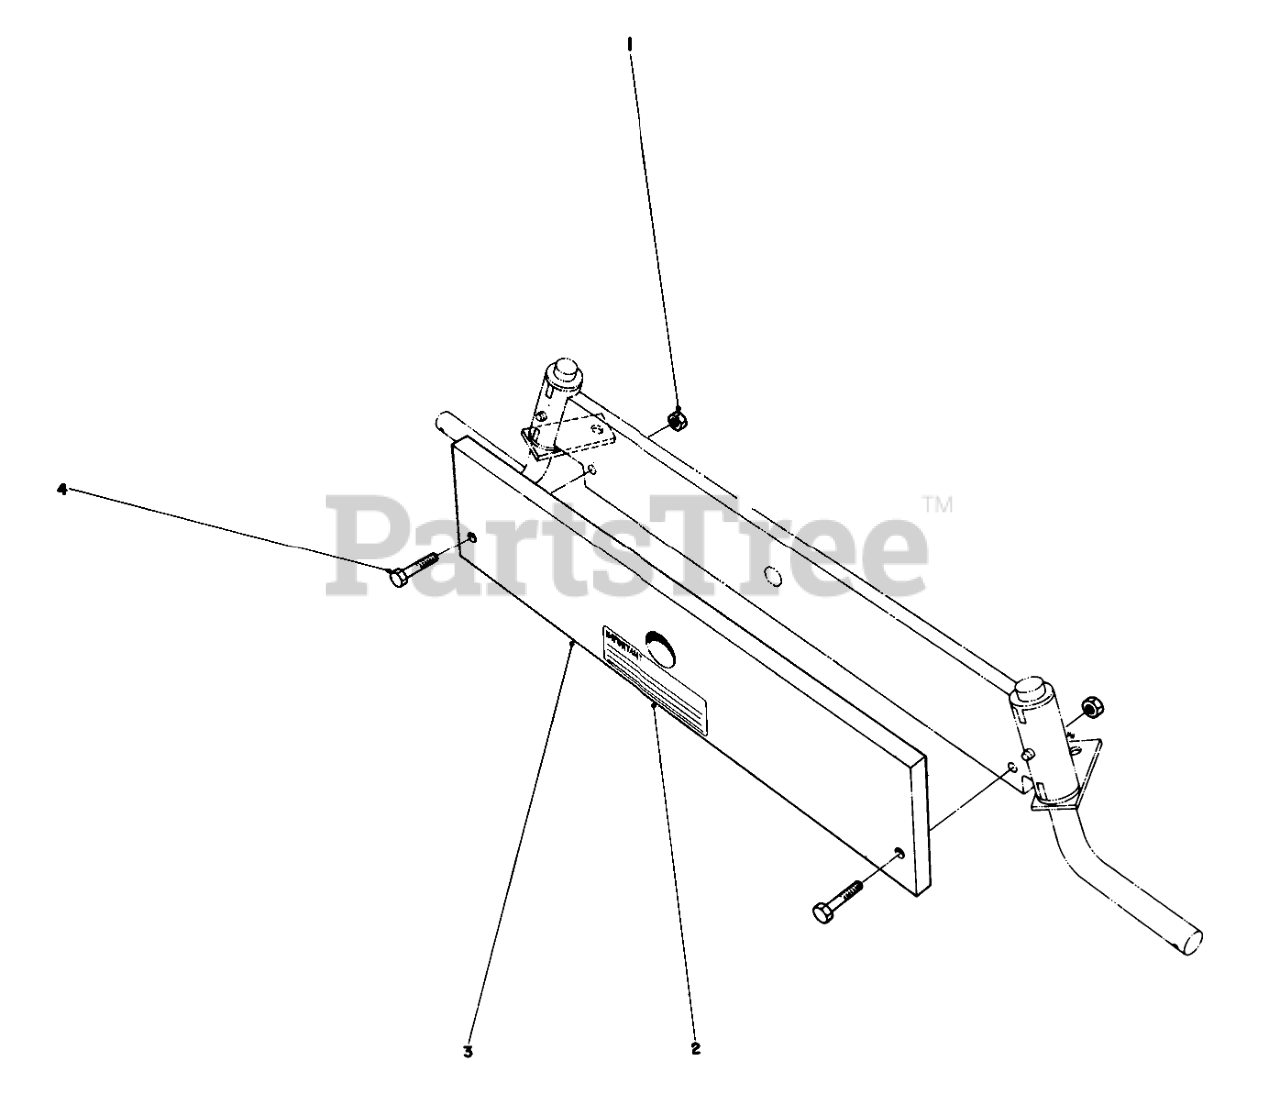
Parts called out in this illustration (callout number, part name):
2	Decal-Instruction
3	Counterweight (Incl. Ref. #2)
4	SCREW-HH
